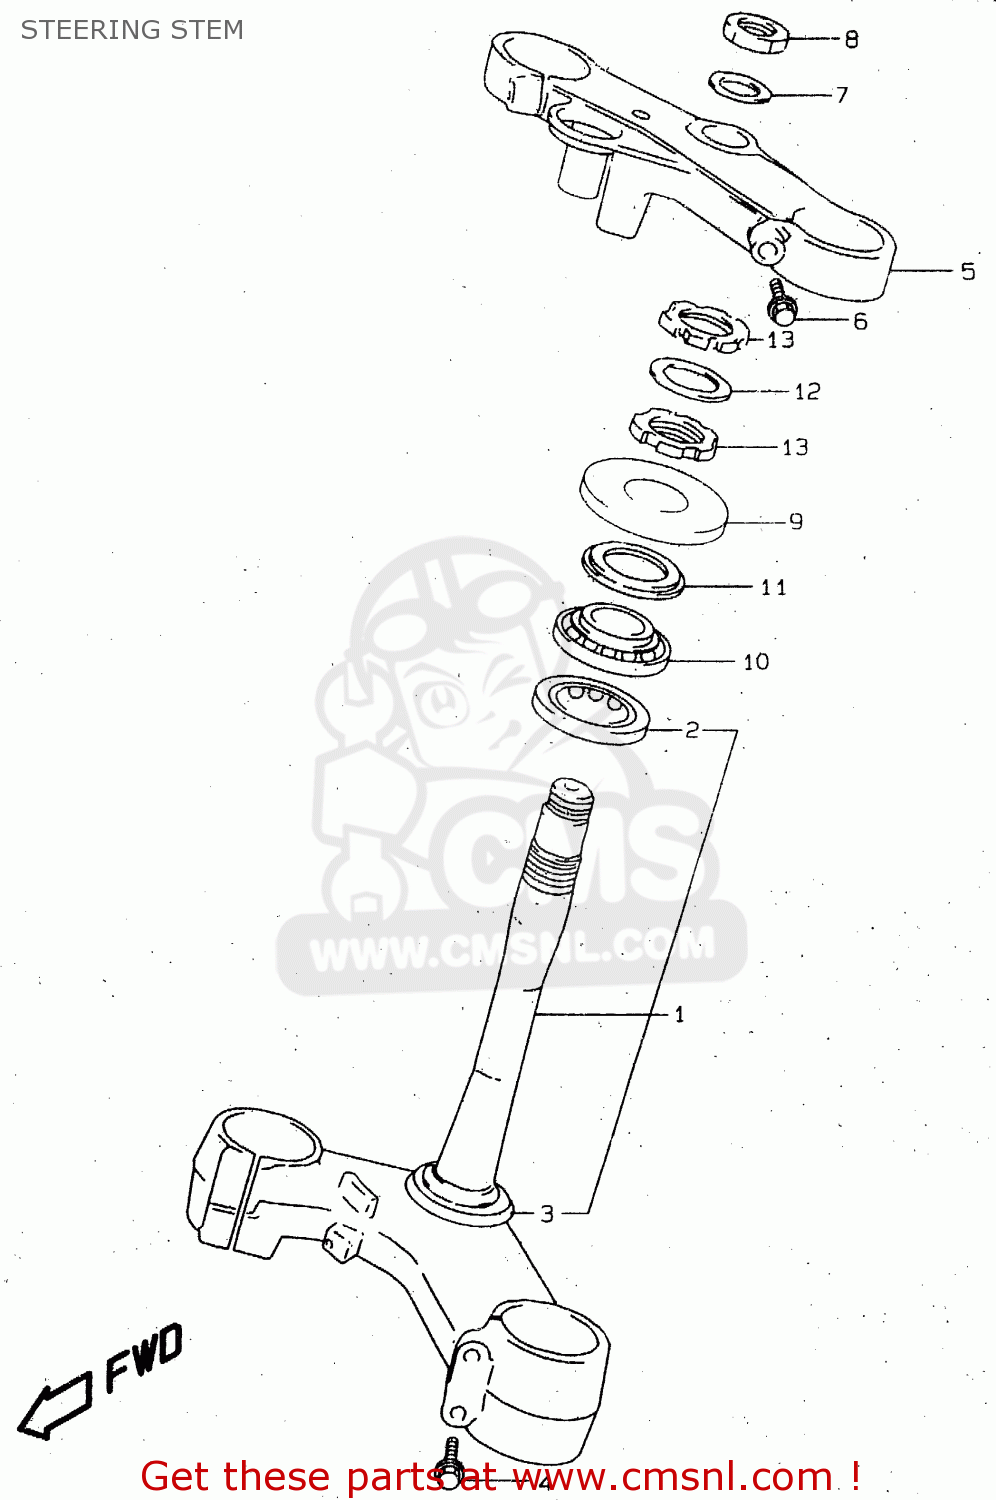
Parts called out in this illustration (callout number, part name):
1	STEM,STEERING
2	BEARING(30X55X17)
3	SEAL,STEERING LWR
4	BOLT
5	HEAD,STEERING STEM
6	BOLT
7	WASHER,STEM HEAD(24.5X34X1.6)
8	NUT
9	SEAL,STEERING LWR
10	BEARING(30X55X17)
11	COVER,STEERING UPR
12	WASHER,STEERING STEM
13	NUT,STEERING STEM
